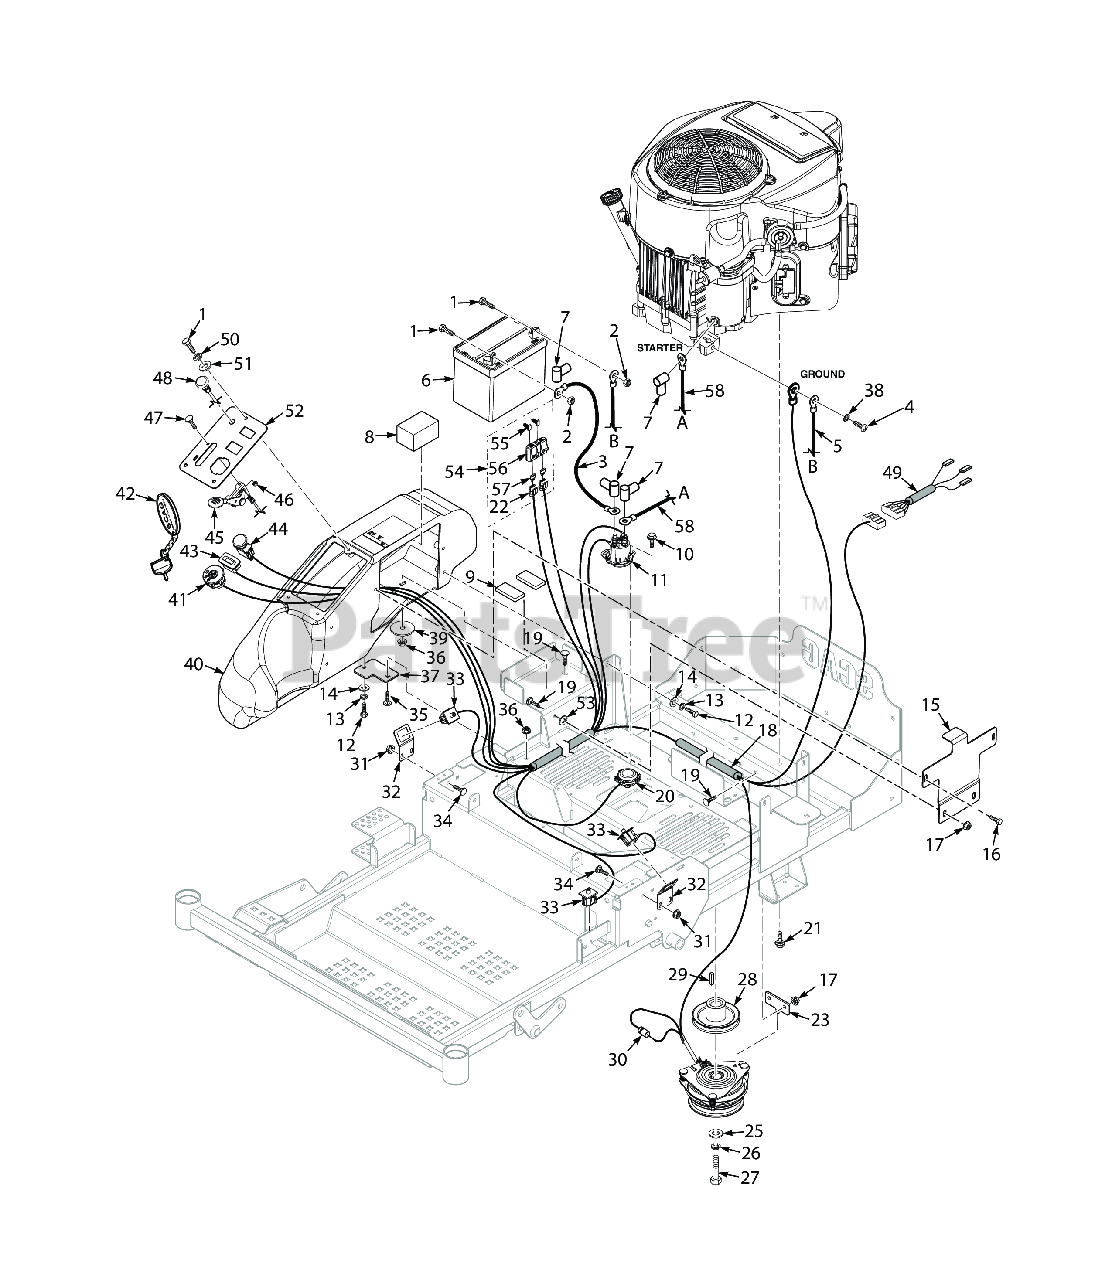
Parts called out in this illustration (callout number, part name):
1	Bolt, Hex Head 1/4-20 x .5" Battery, (Not Available Through Scag)
2	Nut, 1/4 - 20 Hex
3	Battery Cable, 18" Red w/Braid (25KA, 26DFI, 31DFI) - Kawasaki
4	Bolt, Hex Head M8 - 1.25 x 16 (48V / 52V)
5	Battery Cable, 31-1/2" Black (25KA, 26DFI, 31DFI) - Kawasaki
6	Battery, 12v - 230CCA
7	RUBBER BOOT
8	Pad, Battery - Rubber
9	Pad, Battery - Rubber
10	Screw, Self-Tapping 1/4-20 x 3/4
11	Solenoid, Sealed (Briggs & Stratton)
12	BOLT, SERRATED FLANGE HEX HEAD 5/16-18 X 3/4"
13	Lockwasher, 5/16 (.317 x .586 x .078) Helical Spring
14	Flatwasher, 5/16-.375 x .875 x .083 (35BV & 37BV-EFI)
15	Battery Hold Down
16	CAP SCREW, 5/16-18 X 1/2" SERRATED FLANGE HEX
17	Nut, Flange Head Elastic Stop 5/16-18
18	Wire Harness
19	Bolt, 5/16-18 x .75 RHSN Carriage
20	Switch, Double Pole - Twist
21	Bolt, Hex Head Self-Tap 3/8-16 x 1-1/4" (Kohler x3 - 25EFI, Kohler x4 - 29EFI)
22	Fuse Holder Assembly
23	PLATE, ANTI-ROTATION
24	Electric Clutch Assembly
25	Flatwasher, 7/16-.469 x 1.75 x .25 (48, 52)
26	Lockwasher, 7/16� Spring
27	Bolt, Hex Head 7/16-20 x 3" w/t Patch
28	Pulley, 4-1/2" Dia. - 1" Bore
29	Key, 1/4 x 1/4 x 1.25" Pulley Mtg.
30	Diode (part of wire harness)
31	Nut, Flanged Elastic Stop 1/4-20
32	Bracket, Switch
33	Switch, Double Pole - Plunger
34	Serr. Fl. Hex Head CPSCR, 1/4-20 x 3/4"
35	Bolt, Carriage 5/16-18x1" (large frame units only)
36	Nut, Serrated Flange 5/16-18 (Right Front Engine Mounting, Briggs and Kohler Only)
37	Mounting Bracket, Fuel Tank Front
38	Lockwasher, 5/16" Ext. Tooth (Kohler x1)
39	Flatwasher, 3/8-.406 x 2.25" x .1875
40	Console Tank, SZL
41	Ignition Switch
42	Key, Assembly w/Fob
42	Key w/Shroud Only
43	Hourmeter
44	Switch, PTO - 10 Amp
45	Throttle Cable, Briggs & Stratton
46	Nut, Elastic Stop #10-24
47	Bolt, Carriage #10-24 x 1/2"
48	Choke Cable, Briggs & Stratton
50	Lockwasher, 1/4� Spring
51	Flatwasher, 1/4" (.312 x .750 x .065")
52	Instrument Panel w/Decal
53	Nut, Push-On 5/16-18
54	Double Fuse Assy.
55	Clip, Fuse Holder
56	Cover, Sealed Double
57	FUSE, 20 AMP BLADE TYPE AUTOMOTIVE
58	Battery Cable, 18" Red w/Braid (25KA, 26DFI, 31DFI) - Kawasaki
58	Battery Cable, 25" Red (Kawasaki)
